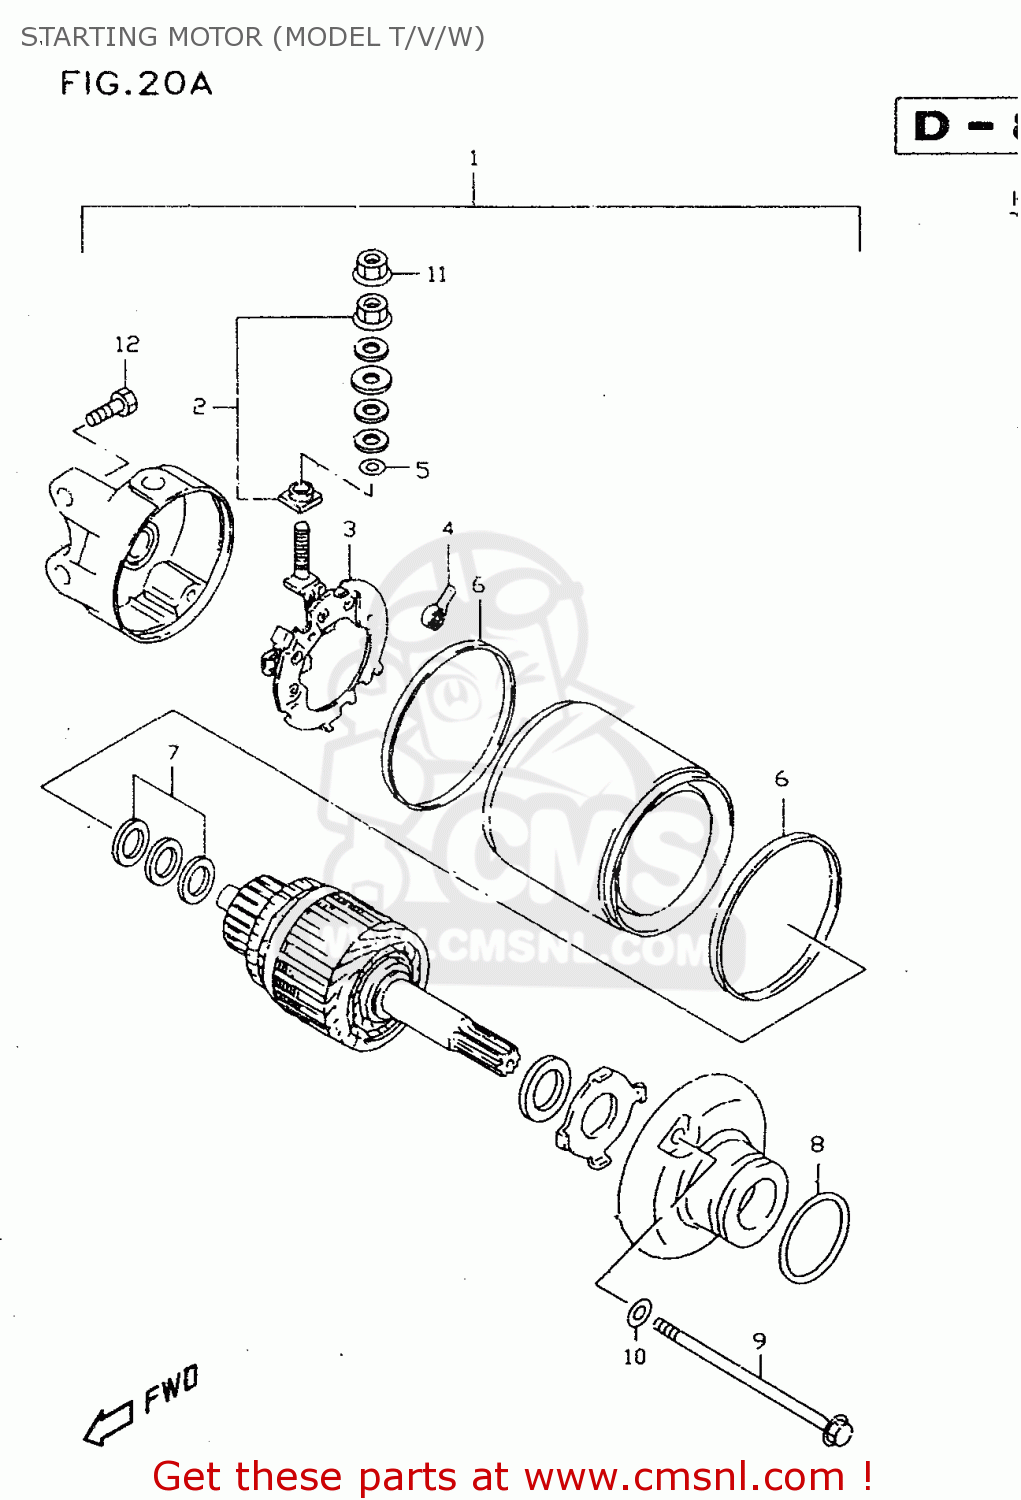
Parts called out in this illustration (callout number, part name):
1	MOTOR ASSY,STARTING
2	BRUSH TERMINAL SET
3	BRUSH HOLDER SET
4	SPRING,BRUSH
5	O RING
6	O RING
7	SHIM SET,STARTING MOTOR
8	O RING
9	SET,BOLT ASSY
10	O RING(D:3,ID:24.5)
11	NUT
12	BOLT,CRKCASE,R
